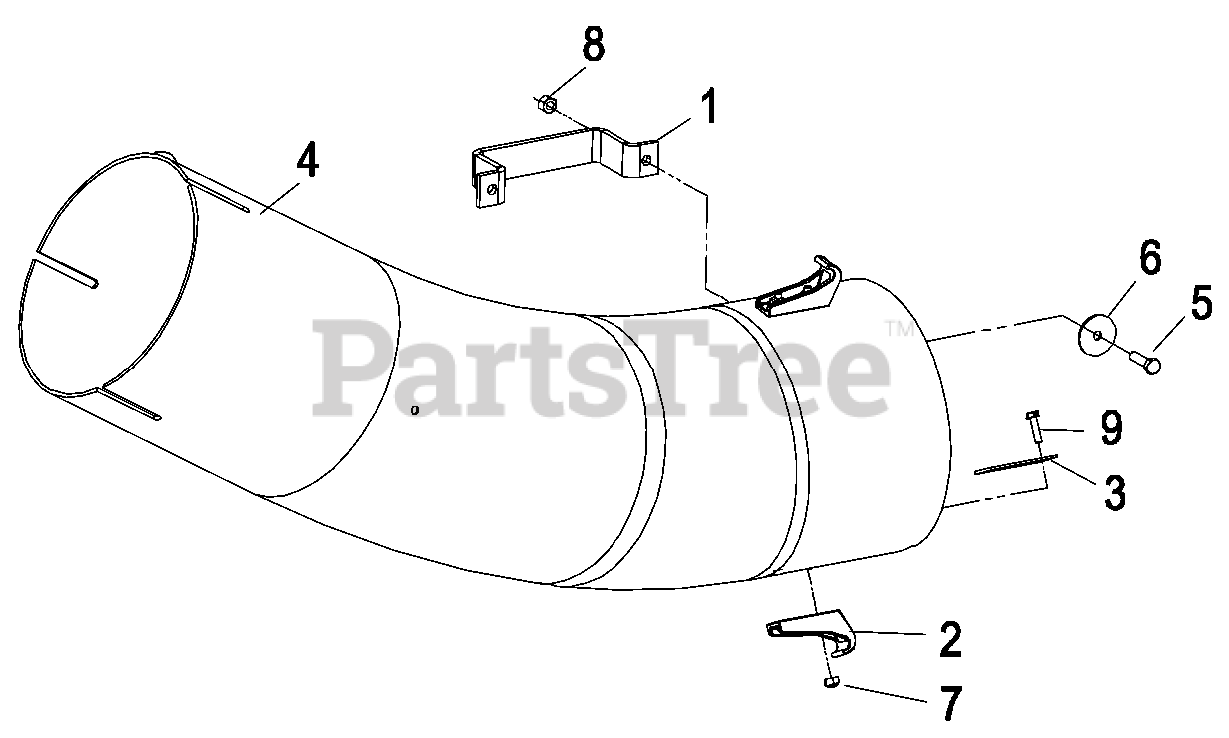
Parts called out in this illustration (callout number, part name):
2	LATCH-CATCH
3	PLATE-BACKING
4	TUBE-LOWER
5	SCREW-HH
6	WASHER-FLAT
7	NUT-LOCK, NI
8	NUT-LOCK, NI
9	SCREW-HWH
